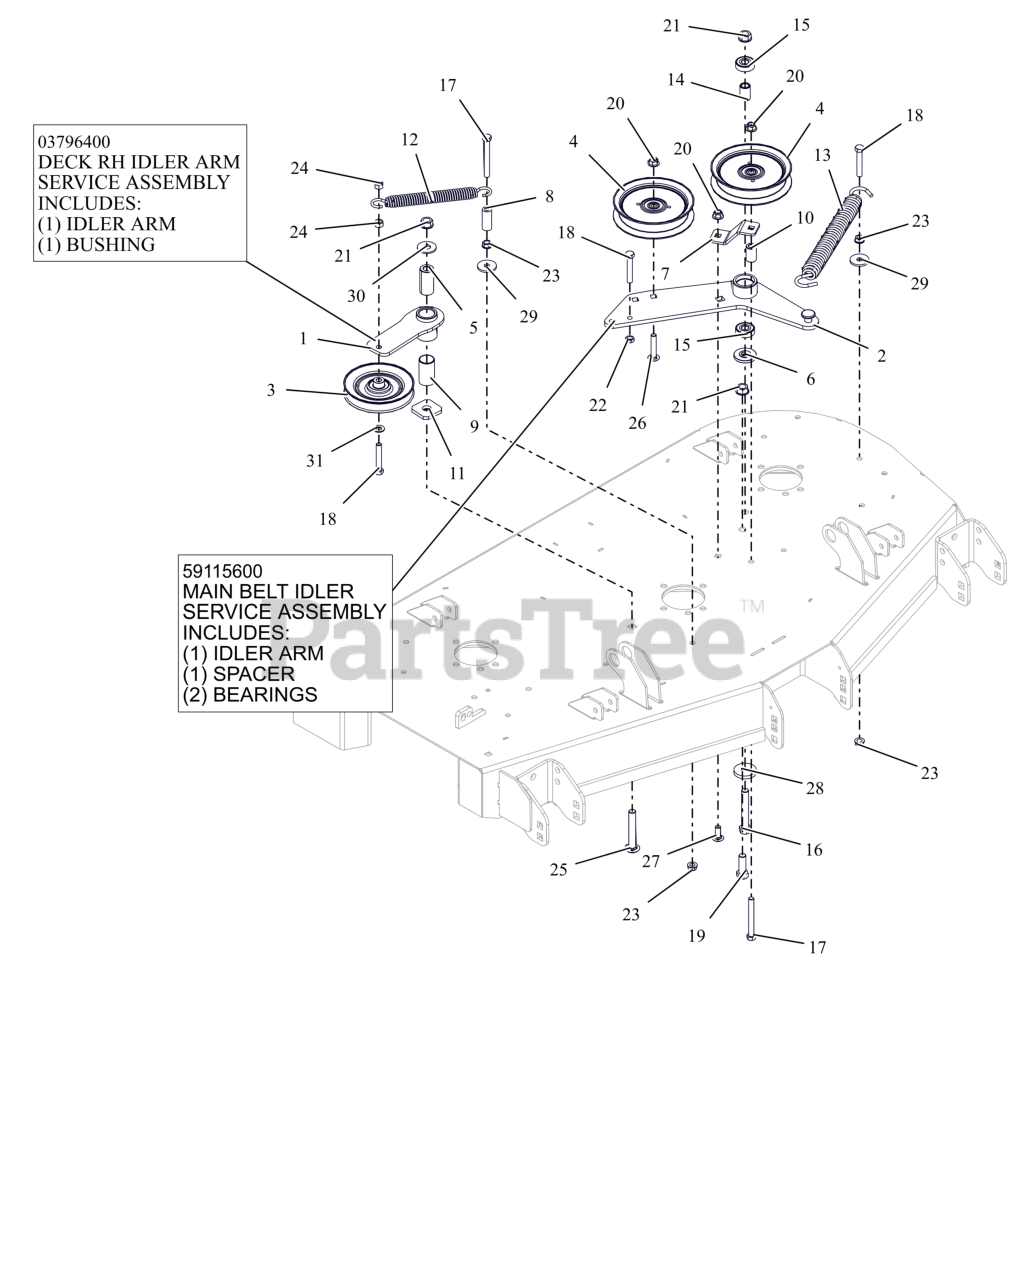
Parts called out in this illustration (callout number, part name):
1	WMT, IDLER ARM - BLACK
1	ASM, IDLER ARM (DECK)
2	WLDMT, DECK PTO IDLR ARM
2	ASSEMBLY, MAIN BELT IDLER
3	IDLER, V-5.00"
4	IDLER, FLAT 5.00"
5	BSHG, SPCR .502X.997X2.03 PM
6	SPACER, IDLER ARM
7	PTO FIXED IDLER MTG BRKT -RED
8	HOSE, .38 X 1.65
9	BSHG, 1.00X1.125X1.937
10	BUSHING, SLV .380X.750X1.190
11	WSHR-FLT .640X1.75X.250
12	SPRING, EXTENSION
13	SPRING, EXTENSION
14	SPACER .510 X .75 X 1.1485
15	BRG-BALL .500X1.38X.437
16	BLT,HEX .50-13X3.25 G5 ZCC
17	BLT, HEX .38-16X3.25 G5 ZCC
18	BLT,HEX .38-16X2.25 G5 ZCC
19	BLT,HEX .50-13X1.50 G5 ZCC
20	NUT,NYL-FLG .38-16 GF ZCC
21	NUT-LK-CTR-FLG .500-13 GG ZCC
22	NUT-JAM .375-16 G2 ZCC
23	NUT, SPNLK-FLG .38-16 G5 ZCC
24	NUT-LK-CTR .38-16 ZC120
25	BTL,RHSSN .500-13 X 3.25 G5 ZCC
26	BLT,RHSSN.375-16X2.00 G5 ZCC
27	BLT,RHSSN .38-16X1.00 G5 ZCC
28	WSHR-FL-STL 0.557X1.625X0.25 ZCC
29	WSHR,FLT .406X1.375X.135 ZCC
30	WSHR,FLT .563X1.375X.109 ZCC
31	WSHR,FLT .406X.812X.065 ZCC
